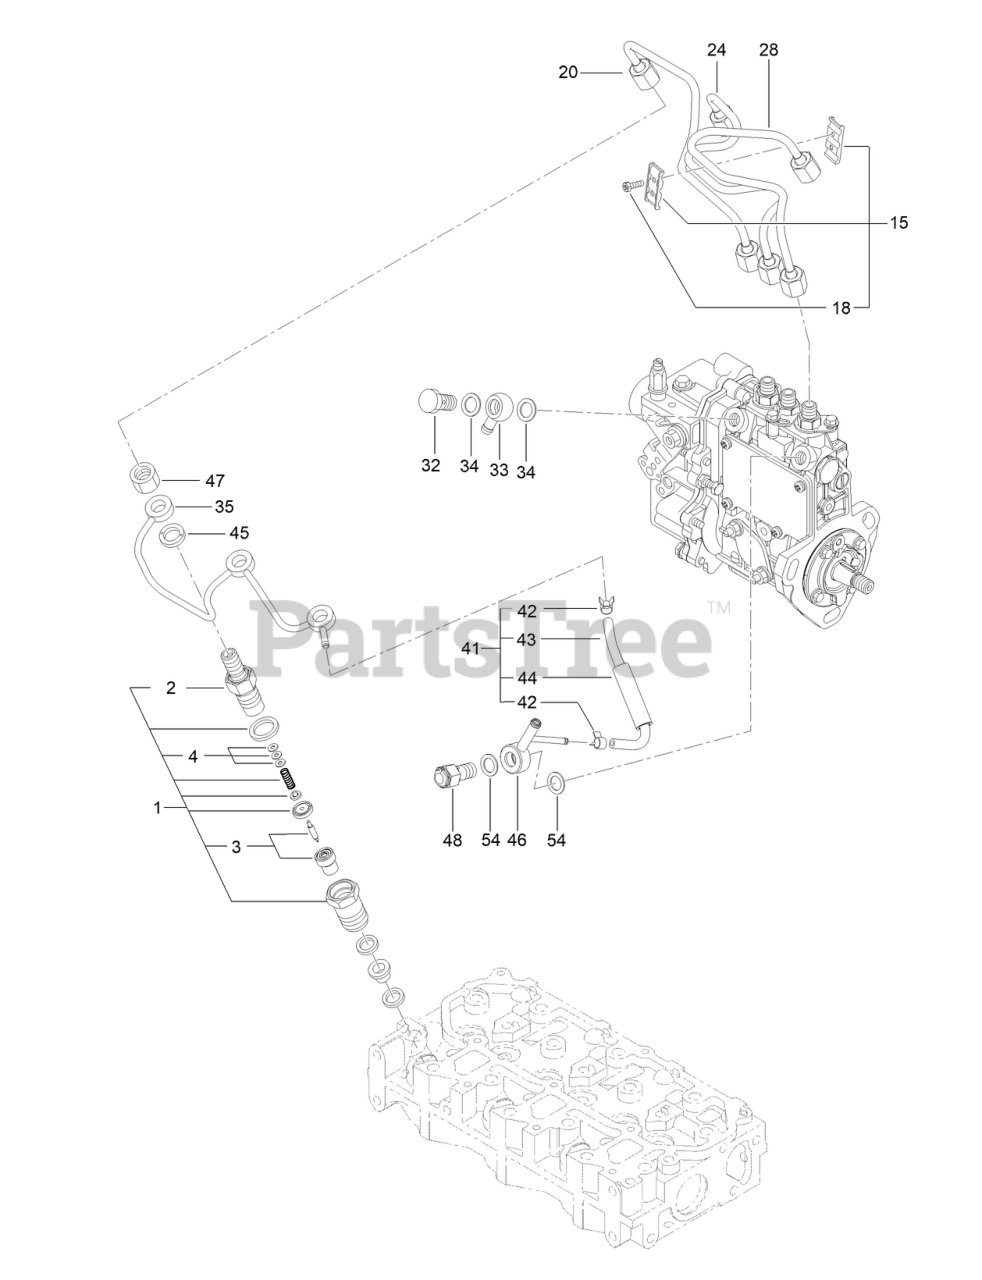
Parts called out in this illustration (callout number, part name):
1	NOZZLE ASM
2	HOLDER-NOZZLE
3	NOZZLE ASM
4	SHIM SET-ADJUSTING
15	RETAINER-PIPE
20	PIPE ASM
24	PIPE ASM
28	PIPE ASM
32	BOLT-PIPE JOINT
33	JOINT-PIPE
34	WASHER-SEAL
35	RETURN PIPE ASM
41	PIPE ASSY, FO RETURN
42	CLAMP-HOSE
43	PIPE, FO RETURN
44	TUBE, CORRUGATED
45	GASKET
46	JOINT-OVER FLOW
47	NUT-NOZZLE
48	VALVE ASM-CHECK
54	WASHER-SEAL
